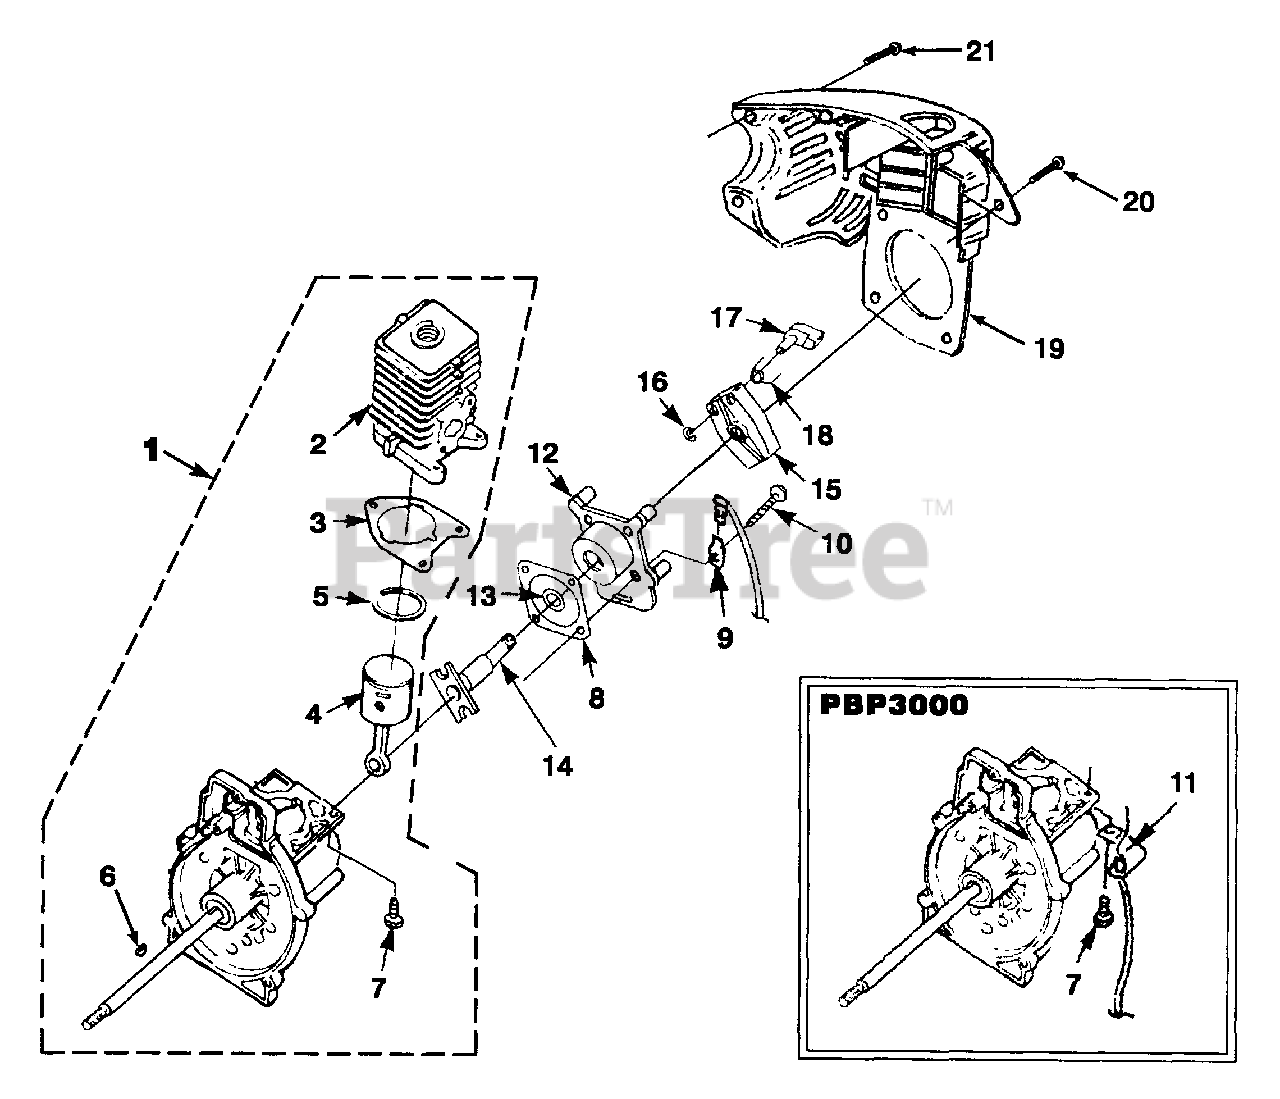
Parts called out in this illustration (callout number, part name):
1	Short Block Kit
2	Cylinder Kit
3	Cylinder Gasket
4	Piston & Rod
5	Piston Ring
6	Woodruff Key
7	Screw-Machine, 12-24 x 3/4"
8	Crankcase Gasket
9	Male Tab
10	Screw-Thread Form. #10-24 x 3/4"
11	Cable Bracket
12	Crankcase Cover
14	Starter Shaft
15	Starter Cup
16	Retaining Ring
17	Starter Pawl
18	Starter Spring
19	Cowling
20	Screw 8 X .500 Pan Hd. Plastite
21	Screw #10 X .500 Plastite
